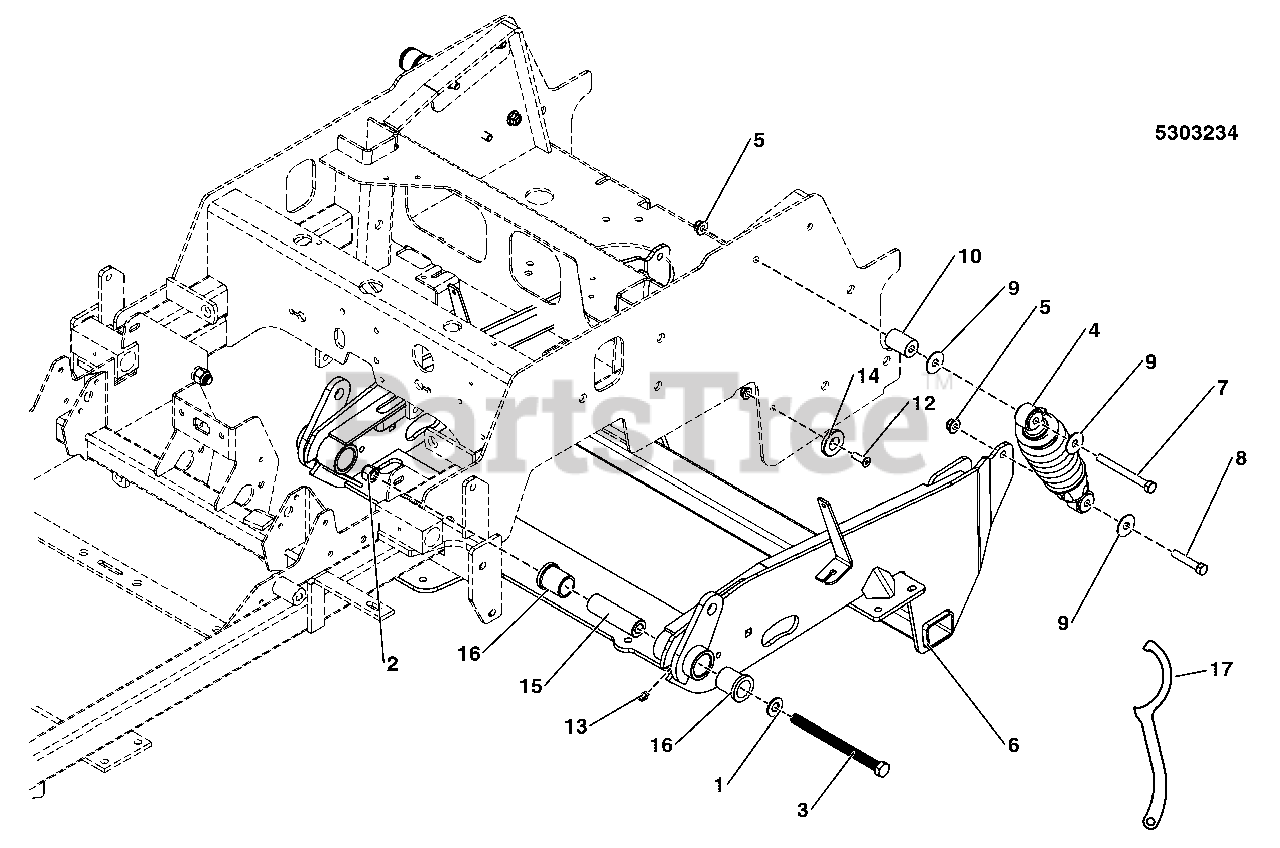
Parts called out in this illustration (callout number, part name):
1	WASHER, 1/2 SAE
2	NUT, 1/2-13 HEX NYLON LOCK
3	BOLT, 1/2-13 X 6-1/2 GD8, YZ
4	SHOCK ABSORBER
5	NUT, 3/8-16 HEX NYLOCK FLANGE
6	WELD, SUSPENSION CRADLE, IS700 - ORG
7	BOLT, 3/8-16 X 3-1/2 GD5 CZ
8	BOLT, 3/8-16 X 2 GD5 YZ
9	WASHER-3/8 FENDER
10	SPACER, .39 X 1.00 X 1.25, CZ
12	SCREW, 5/16-18 X 1, PHILLIPS HD, BZ
13	GREASE FITTING, 1/4-28 STRAIGHT
14	SPACER, .34 X 1.54 X .25 - UHMW
15	SPACER, .52 X 1.00 X 3.42
16	BUSHING, FLANGE
17	WRENCH, SPANNER, CZ
